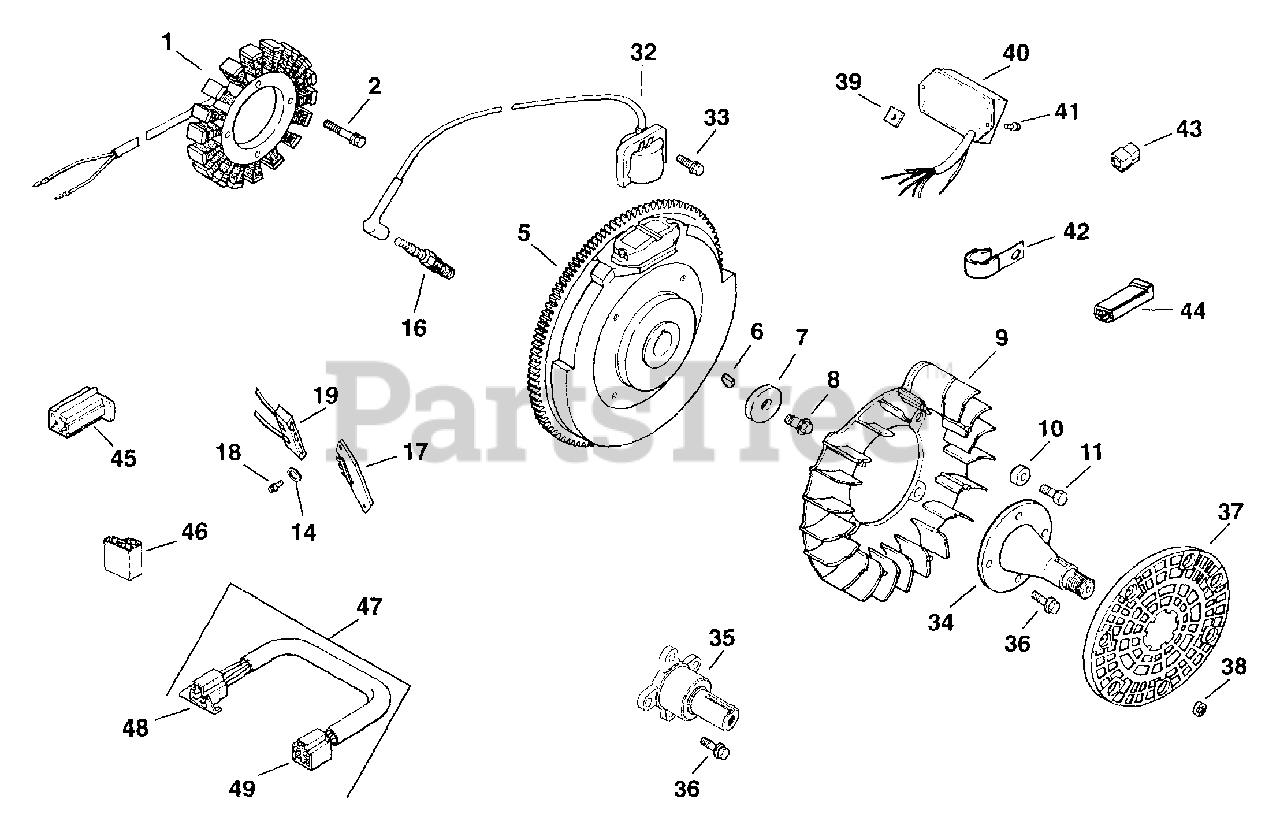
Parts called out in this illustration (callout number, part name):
1	KIT - USE 54 755 09
2	SCREW - USE M-548025
6	KEY, 3/16" X 5/8"
7	WASHER, FLAT 13/32"
8	SCREW, FLG M10X1.5X45 - (#25086361S)
9	FAN (KM)-USE 24 157 15-S
10	BOLT - USE 25 086 47
11	SCREW - USE M-639016
14	WASHER, FLAT 3/16"
16	PLUG, SPARK (STD)
18	SCREW, PHL HD #11-16X7/8"
19	CONNECTOR, BODY (KM)-USE 25 155 41-S
43	CONNECTOR
44	CONNECTOR (1 CONTACT)
2417621	KIT - USE 54 755 02
2451804	LEAD - USE 25 518 34
2451806-S	LEAD - DISCONTINUED
